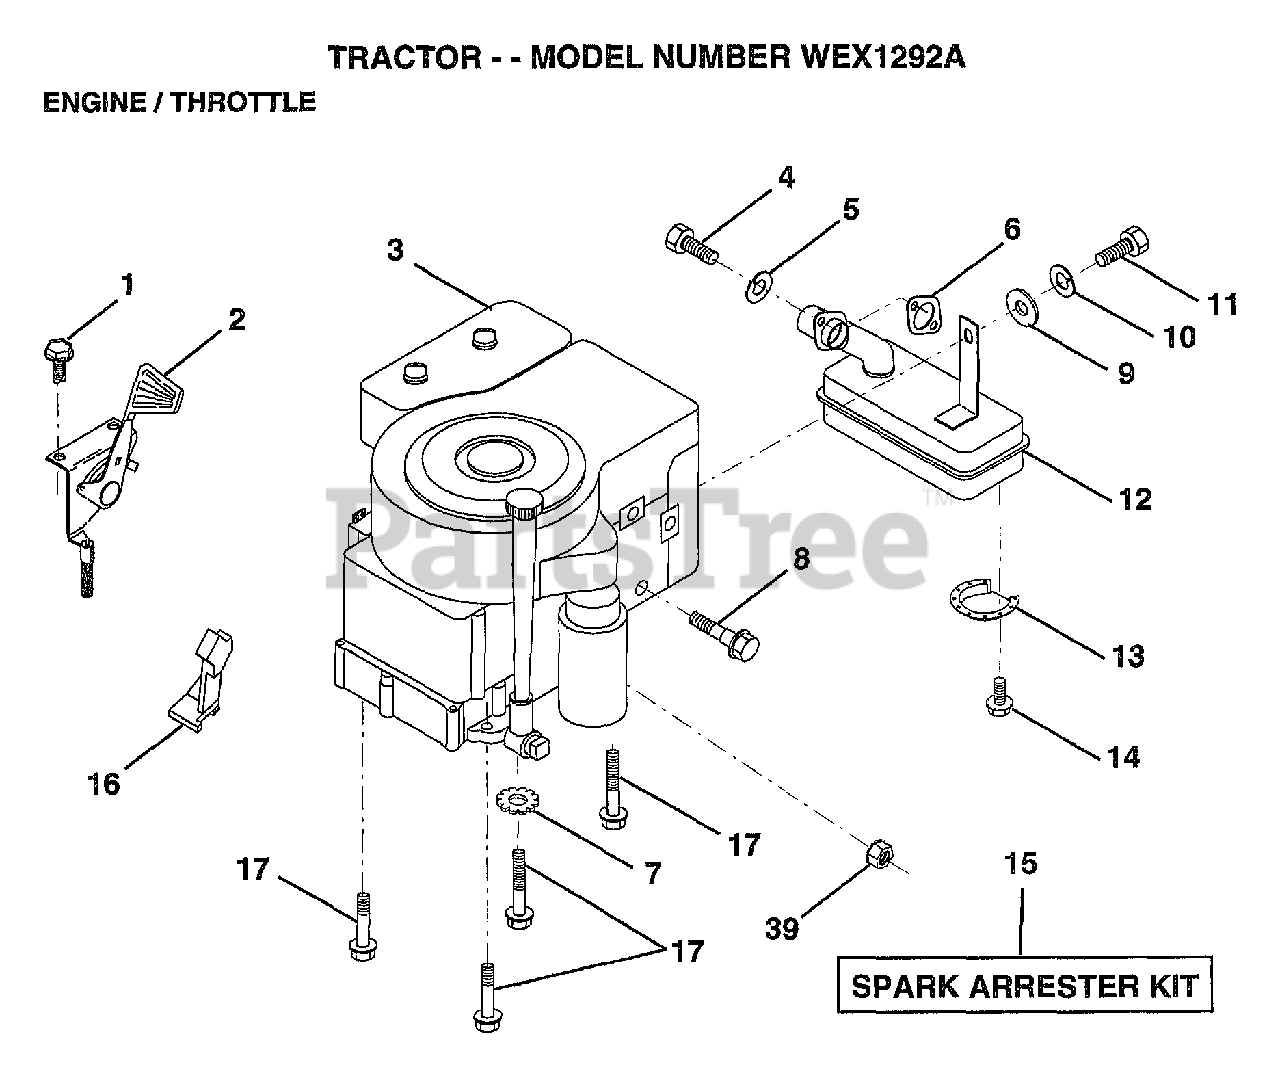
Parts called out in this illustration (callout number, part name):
1	SCREW.1/4-20X1/2
2	"CONTROL,THROTTLE"
4	SCREW HEX HD CAP
5	LOCKWASHER
7	LOCKWASHER
8	SHOULDER BOLT ST
12	MUFFLER-TECH 13HP
13	DEFLECTOR.222573
17	SCREW LT
39	NUT
41	"NUT HEX,LOCK,FLAN"
